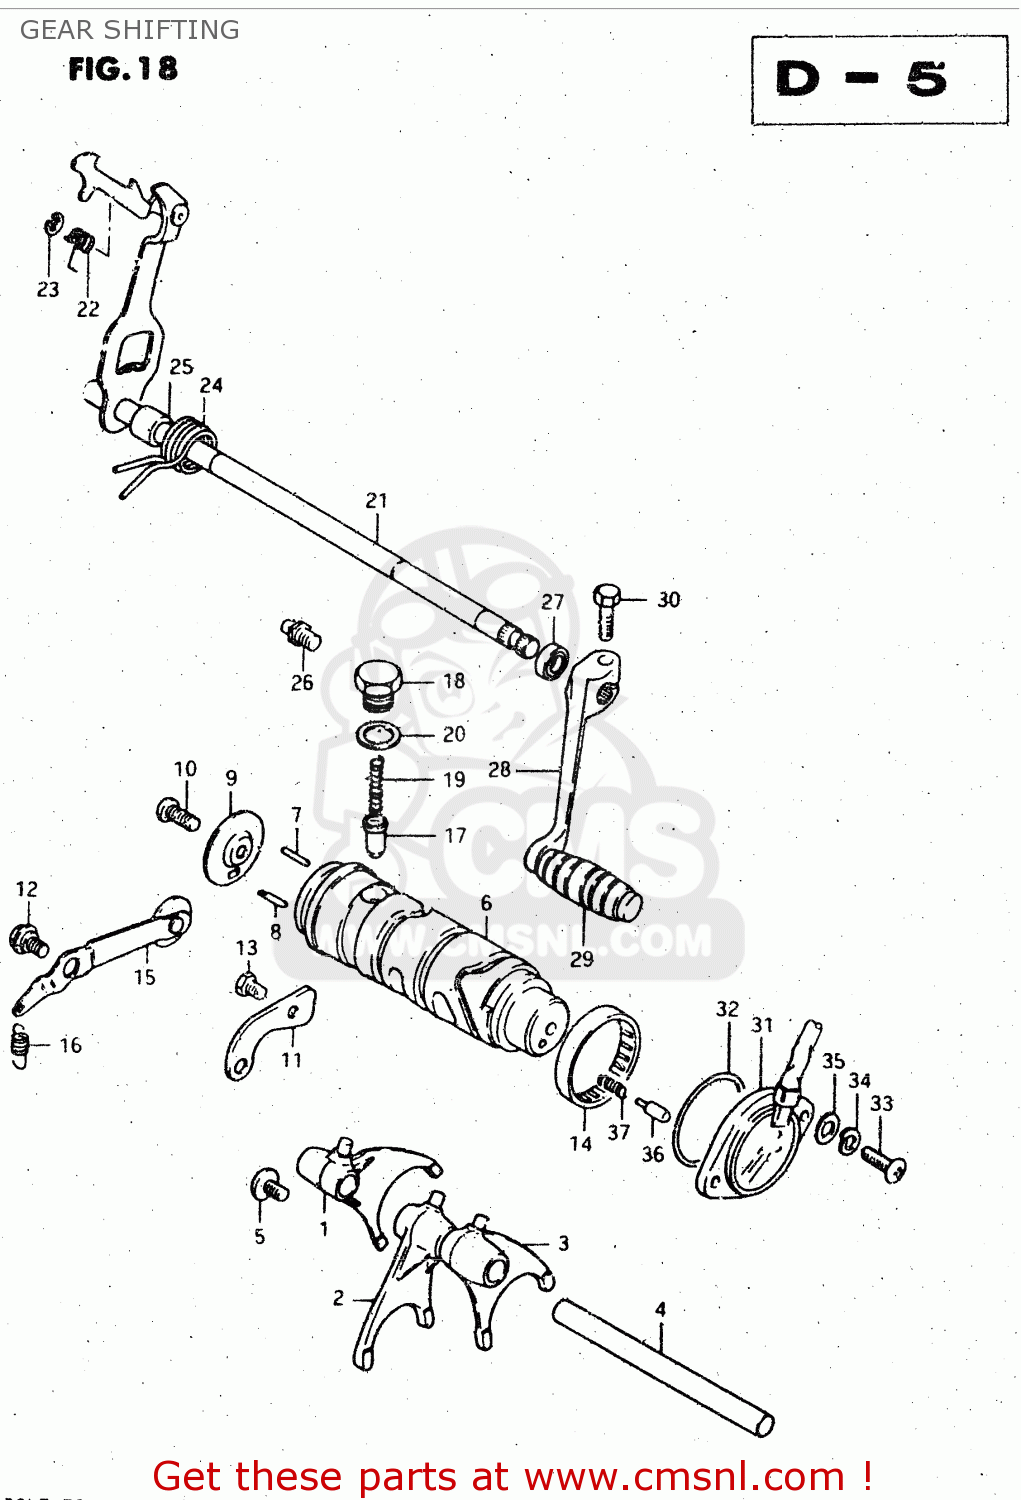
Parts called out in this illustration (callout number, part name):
1	FORK,GEAR SHIFT NO.1
2	FORK,GEAR SHIFT NO.2
3	FORK,GEAR SHIFT NO.2
4	SHAFT,GEAR SHIFT FORK
5	SCREW
6	CAM,GEAR SHIFT
7	PIN(4X18.5)
8	PIN
9	RETAINER,GEAR SHIFT CAM DR PIN
10	SCREW
11	GUIDE,GEAR SHIFTING CABLE
12	BOLT
13	BOLT, UPPER
14	BEARING(40X47X12)
15	STOPPER,GEAR SHIFT CAM NO.1
16	SPRING
17	STOPPER,GEAR SHIFT CAM NO.2
18	HOLDER,GEAR SHIFT CAM STOP SPR
19	SPRING
20	GASKET(14X19.2X2) (NAS)
21	SHAFT,GEAR SHIFT
22	SPRING
23	E RING
24	SPRING
25	SPACER(12X20X15.3)
26	STOPPER,GEAR SHIFT CAM
27	OIL SEAL
28	LEVER ASSEMBLY,GEAR SHIFTING
29	RUBBER,GEAR SHIFT PEDAL
30	BOLT
31	TERMINAL BASE ASSY,GEAR SHIFT
32	O-RING (D:2.4 ID:26.2)
33	SCREW 5X20
34	LOCK WASHER
35	WASHER
36	PIN(5X15.5)
37	SPRING
